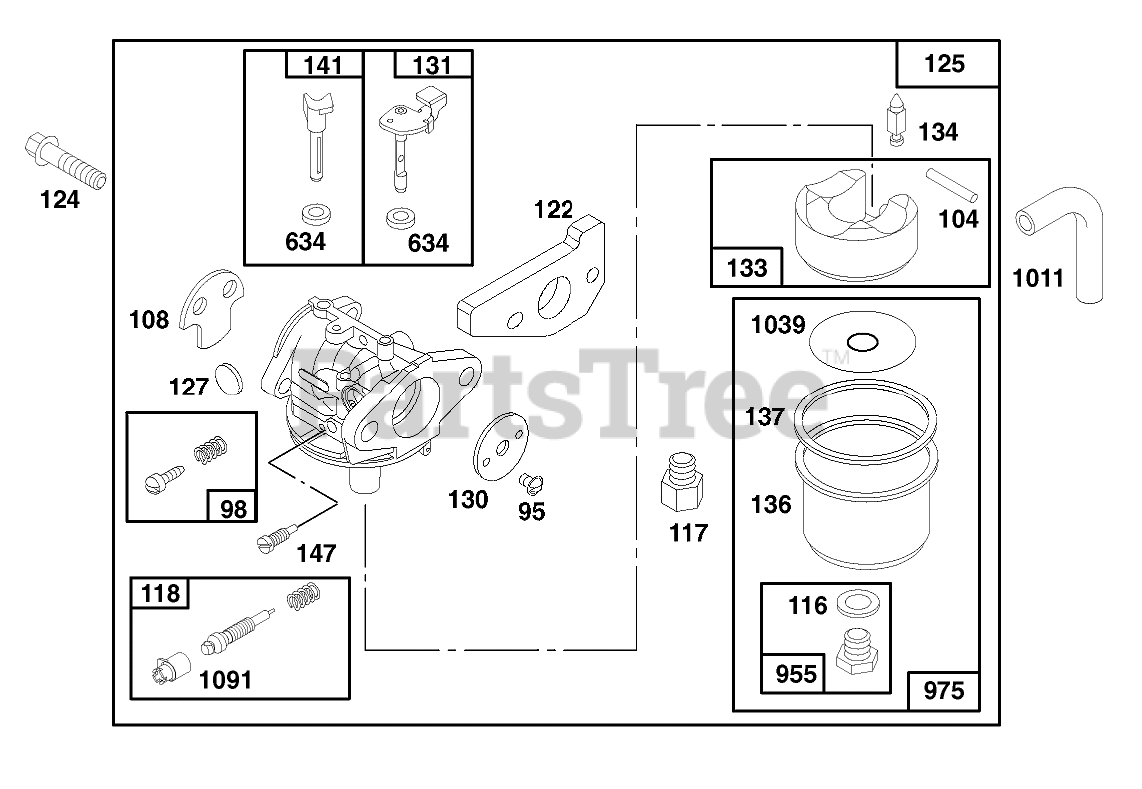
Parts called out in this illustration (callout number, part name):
95	SCREW - ROUND HEAD
98	IDLE ADJUSTING SCREW
104	FLOAT HINGE PIN
108	VALVE - CHOKE
116	SEALING GASKET
117	Jet-Main
118	VALVE/SPRING - NEEDLE
122	ADAPTER ASSEMBLY
124	HEX HEAD SCREW
125	ASSEMBLY - CARBURETOR
127	PLUG - WELCH
130	THROTTLE VALVE
131	THROTTLE SHAFT
133	FLOAT-CARBURETOR
134	Valve-Inlet (Includes Seat)
136	FLOAT BOWL
137	FLOAT BOWL GASKET
141	CHOKE SHAFT
147	JET - PILOT
634	SEAL WASHER
955	HEX HEAD SCREW
975	CARBURETOR BOWL ASM
1011	VENT TUBE
1039	FLOAT LIMITER
1091	CAP - LIMITER
